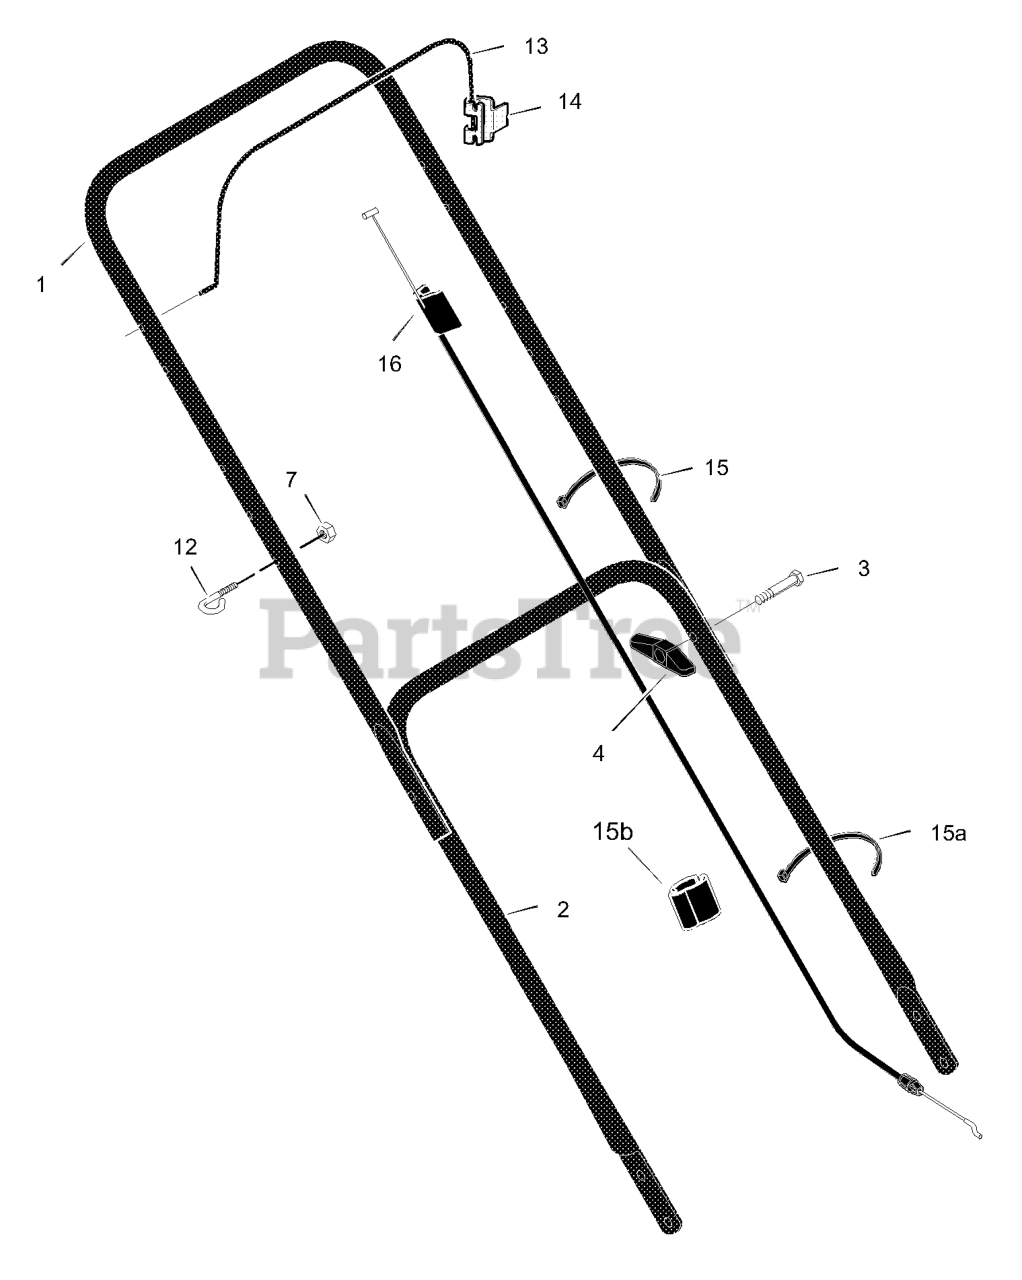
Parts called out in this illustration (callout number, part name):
1	Handle, Upper (Black)
2	Handle, Lower (Black)
4	Knob, Plastic
7	Locknut
12	Guide, Rope
13	Lever, Engine Stop
14	Bracket, Stop Lever
15A	Tie, Cable
15B	Fastener, Cable
16	Cable, Engine Stop
